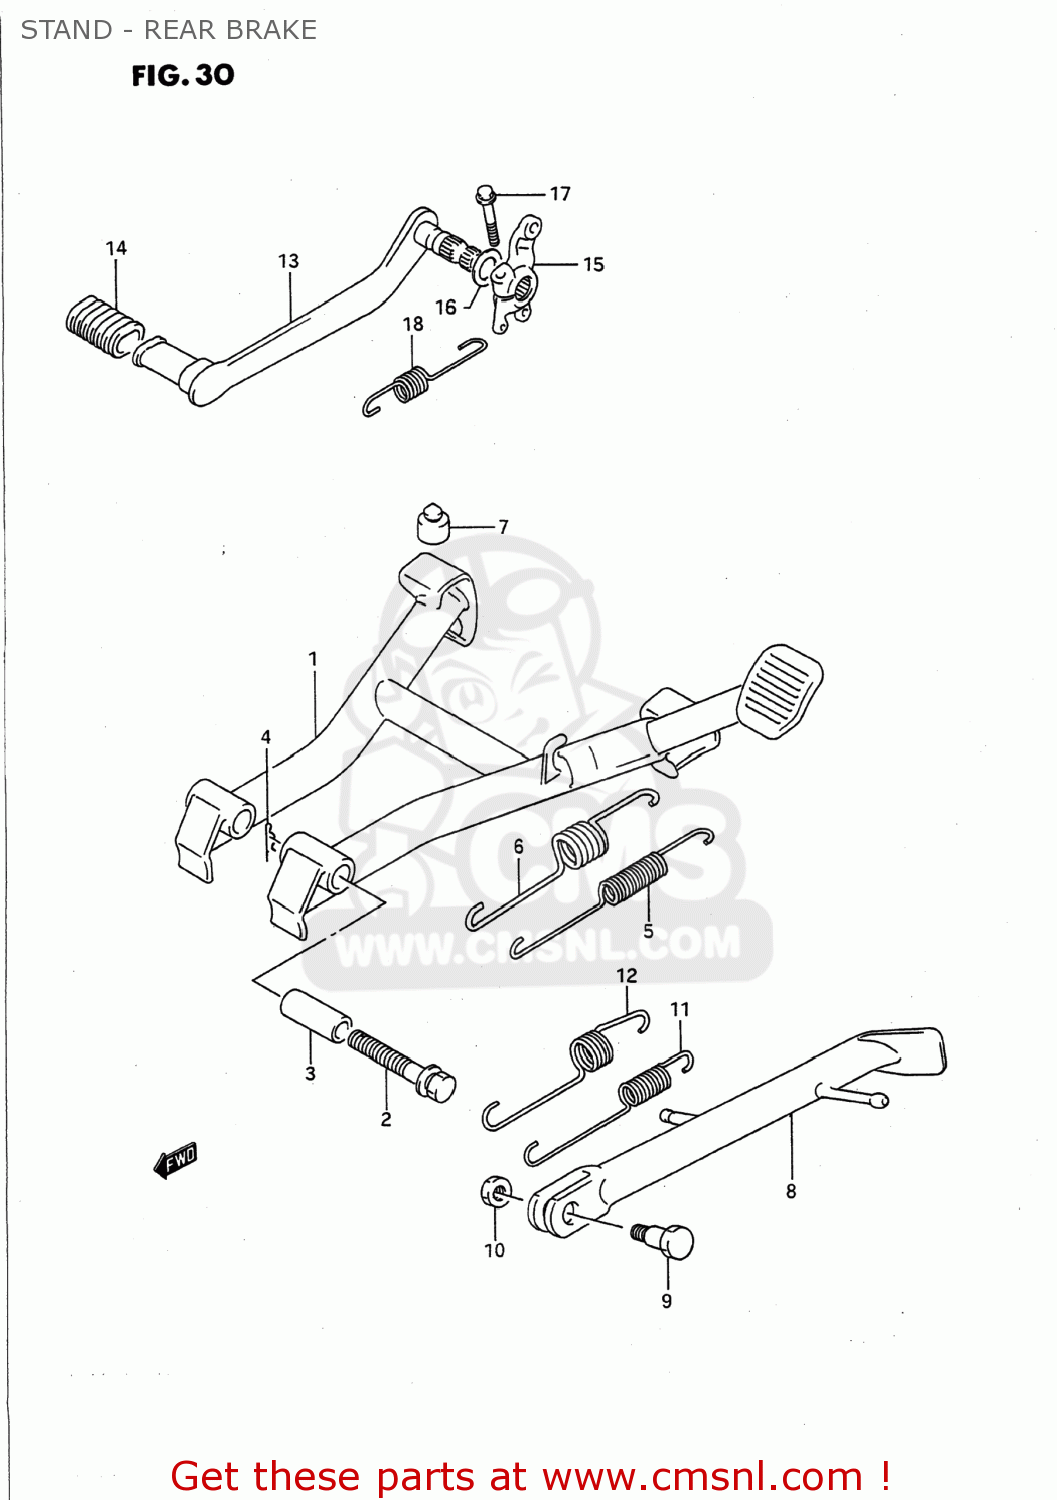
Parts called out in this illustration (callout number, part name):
1	STAND,CTR
2	BOLT
3	SPACER(10X16X38.8)
4	CLIP
5	SPRING
6	SPRING OUTER
7	CUSHION
8	STAND,PROP(BLACK)
9	BOLT L:30
10	NUT
11	SPRING
12	SPRING
13	PEDAL,BRAKE
14	RUBBER,PEDAL
15	ARM,BRAKE ROD
16	WASHER
17	BOLT
18	SPRING
